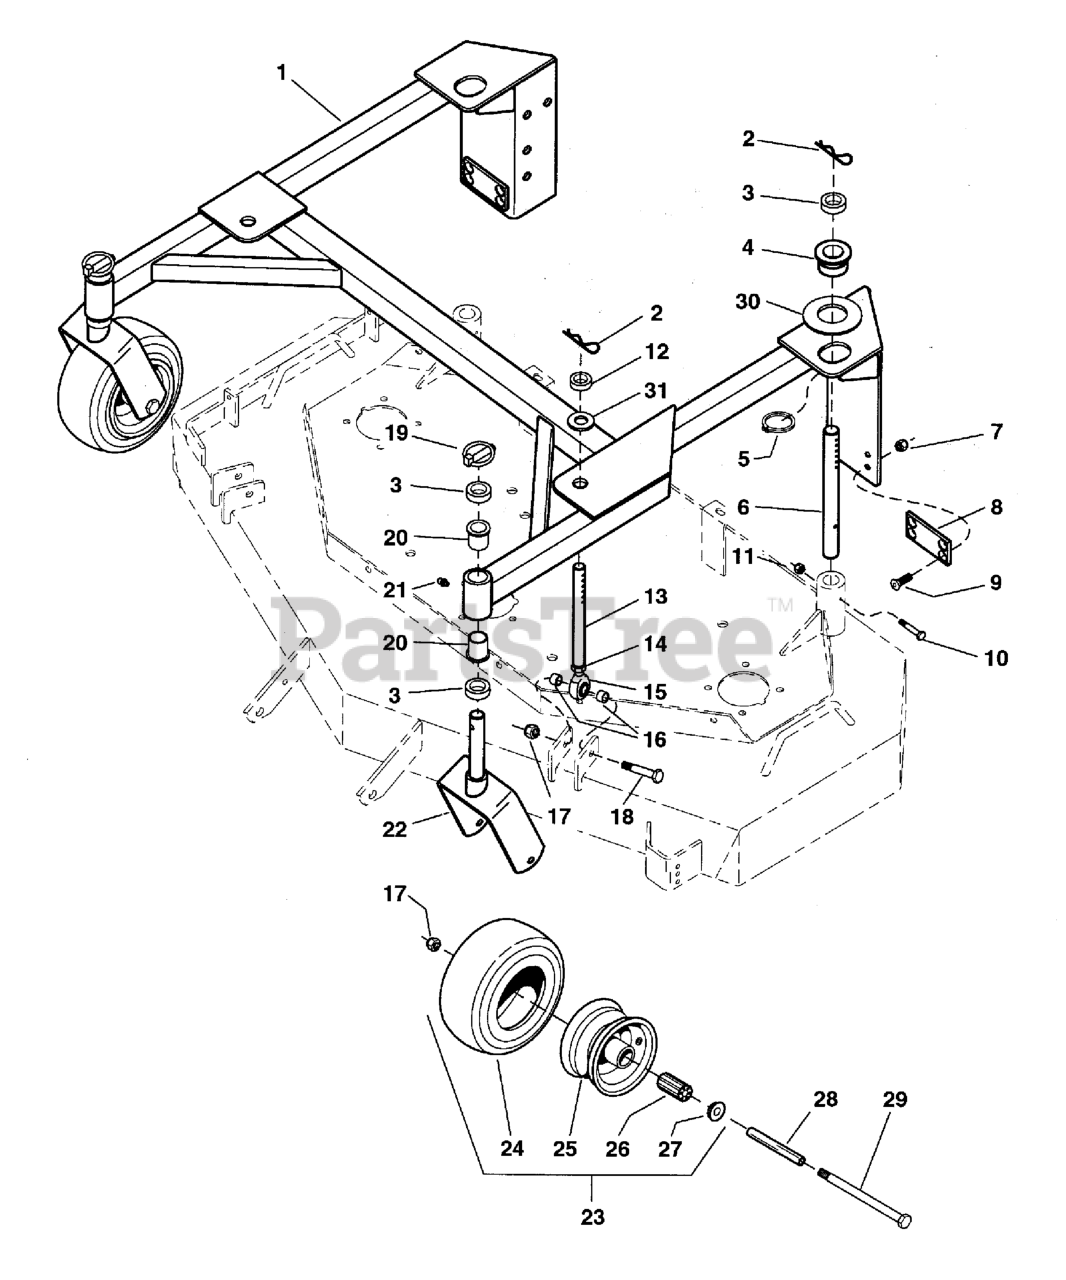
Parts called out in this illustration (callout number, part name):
1	52" MOUNT FRAME
2	HAIRPIN CLIP
3	SPACER, 1.02 x 1.56 x .50
4	DECK HEIGHT BUSHING
5	SNAP RING, External
6	ADJUSTMENT ROD, Rear
7	NUT, 5/16-24 HEX NYLON LOCK
8	FRICTION PLATE
9	SCREW, 5/16-18 X 1 PHILLIPS HD, BZ
10	BOLT, 1/4-20 x 2-1/4
11	NUT, 1/4-20 HEX NYLON LOCK
12	SPACER, .76 x 1.25 x .50
13	ADJUSTMENT ROD, Front
14	NUT, 1/2-20 Hex
15	BALL JOINT, 1/2-20 Male
16	INSERT, Bearing
17	NUT, 1/2-13 HEX NYLON LOCK
18	BOLT, 1/2-13 X 3" GD5 CZ
19	PIN, Lynch
20	BUSHING, FLANGE
21	GREASE FITTING
22	CASTER YOKE
24	TIRE, Front 11 x 4.0 x 5
25	WHEEL ASSEMBLY, for 11 x 4.0 x 5 Tires, Complete
26	BEARING, Roller
27	RETAINER, Bearing
28	AXLE, Front Caster
29	BOLT, 1/2-13 x 6-1/2
30	WASHER, 1-1/2" SAE
31	WASHER, 3/4 SAE
